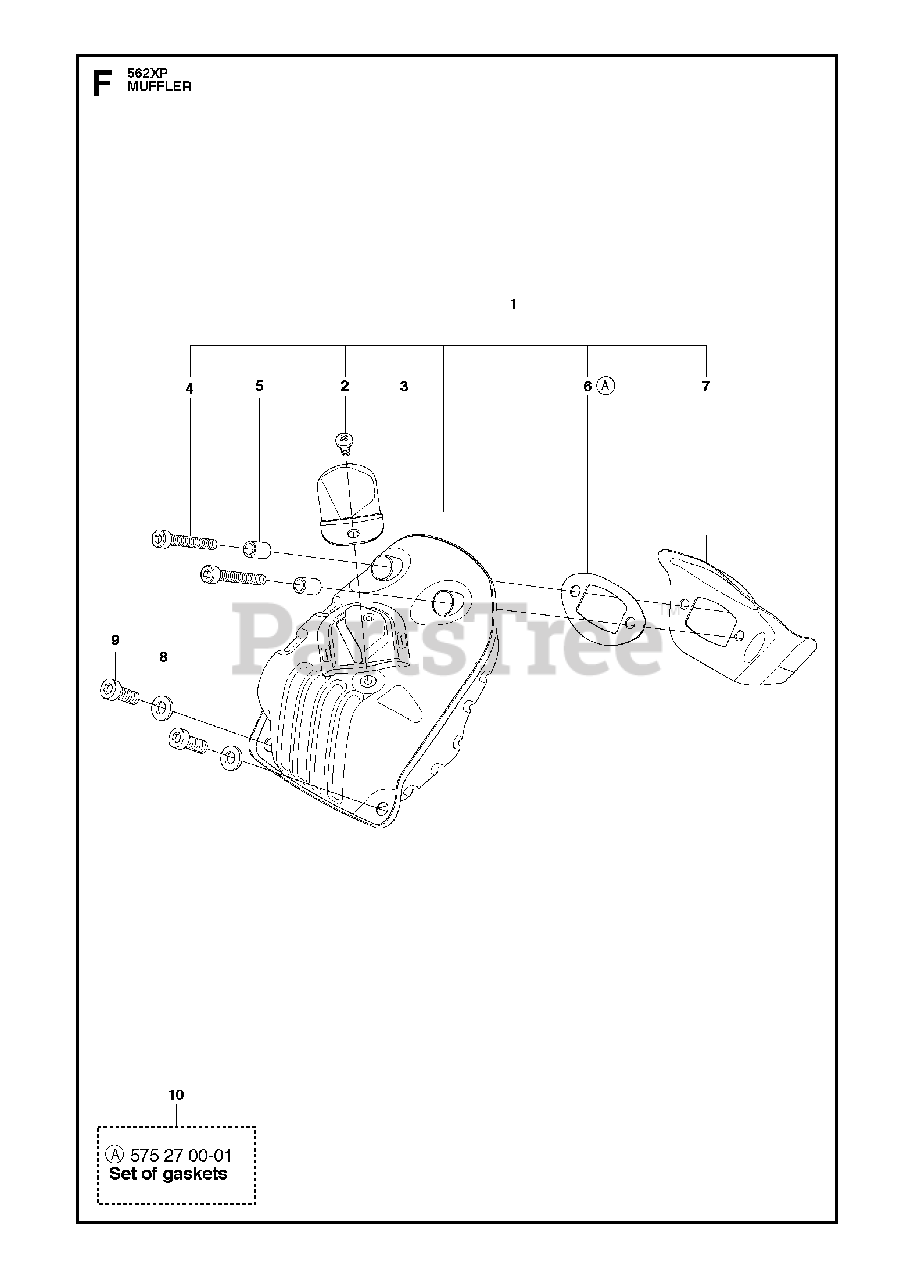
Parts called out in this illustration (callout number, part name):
1	MUFFLER KIT
2	SCREW
3	SPARK ARRESTER
4	SCREW
5	SLEEVE MUFFLER
6	GASKET MUFFLER
7	HEAT DEFLECTOR
8	WASHER
10	RP GASKET KIT
